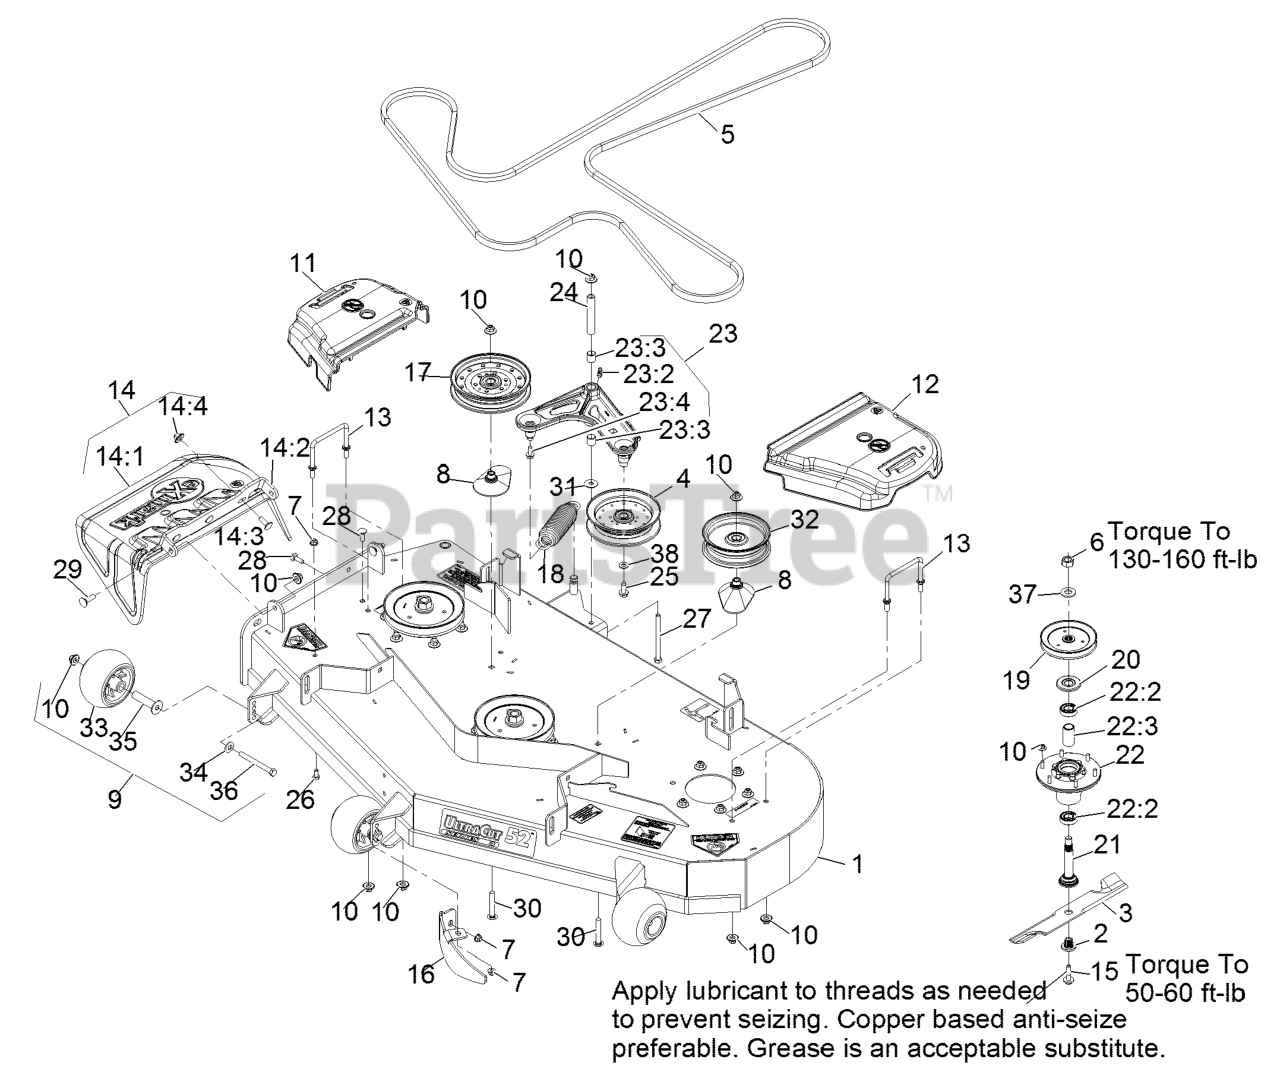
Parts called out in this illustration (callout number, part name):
1	ASM-DECK W/DECALS, 52
2	BUSHING,SPLINED
5	BELT-B162.50
6	NUT-HEX
7	NUT-HF, NI
8	SPACER-PULLEY
9	KIT, ANTI-SCALP ROLLER
10	Nut-Nyloc 3/8-16 Flg
11	COVER-BELT, RH
12	COVER-BELT, LH
13	WIREFORM-COVER
14	ASM,DISCHARGE CHUTE
14:1	CHUTE,DISCHARGE
14:2	BRACKET,DISCHARGE CHUTE
14:3	SCREW-CARR
14:4	Nut-Nyloc 3/8-16 Flg
15	SCREW,SEMS 1/2-20 X 2.19
16	BAFFLE-DOGLEG, LZE-PNS-52
18	SPRING-EXTENSION
19	SHEAVE,BLADE DRIVE 6.50
20	GUARD,BEARING TOP .989
21	ASM-SPINDLE AND SEAL
22	ASM-CUTTER HSG WITH BEARINGS
22:2	BEARING-BALL
22:3	SPACER-BEARING
23	IDLER ARM ASM
23:2	FITTING-GREASE, 90 DEG
23:3	SLEEVE-BEARING
23:4	SCREW-THD ROLL, HWH
24	BUSHING
25	SCREW-FORMING, THREAD
26	SCREW-HH
27	SCREW-HH
28	BOLT-CARR
29	BOLT-CARR
30	SCREW-CARR
32	IDLER-PULLEY, FLAT
33	ROLLER-SCALP, ANTI
34	WASHER-BELLEVILLE
35	AXLE, ROLLER
36	SCREW-HH 3/8-16 X 3 3/4 GR 8
38	WASHER-FLAT
